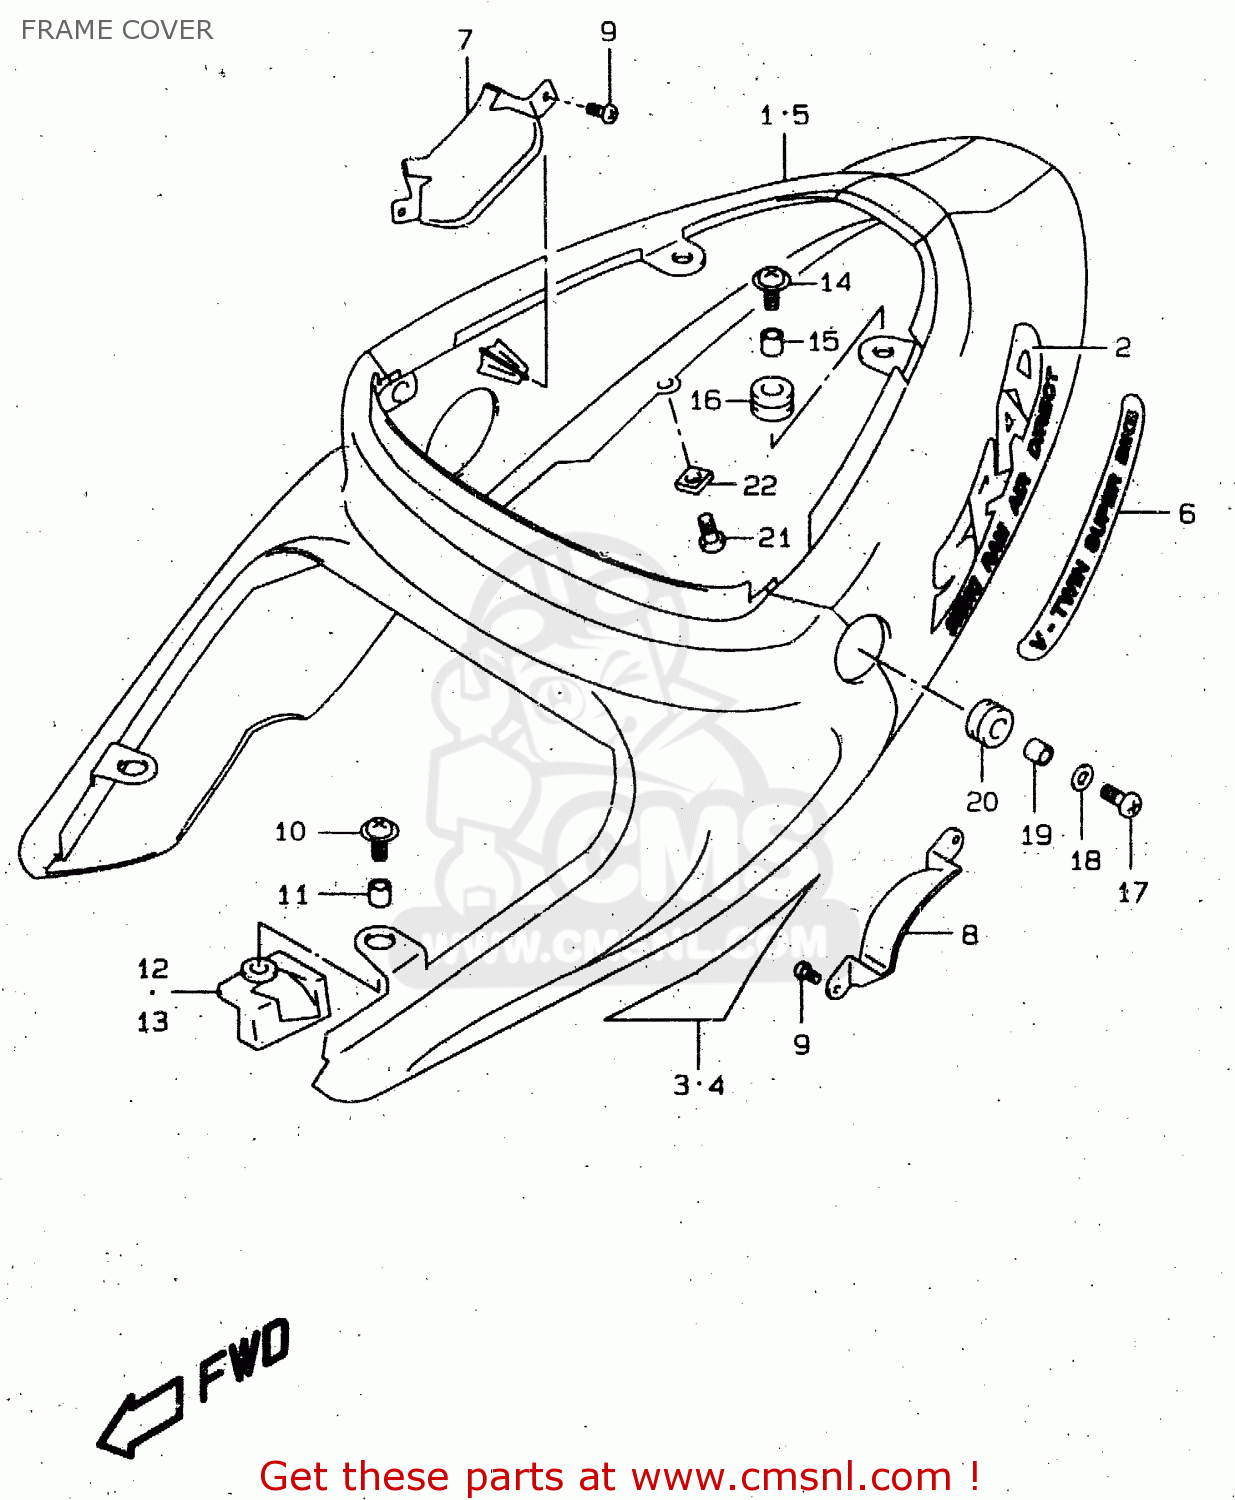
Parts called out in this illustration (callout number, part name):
1	COVER,FRAME,RIGHT
2	EMBLEM,FRAME COVER
3	TAPE,FRAME COVER,R(BLUE)
4	TAPE,FRAME COVER,L(BLUE)
5	COVER,FRAME
6	EMBLEM,FRAME COVER
7	CAP,FRAME COVER HOLE,R
8	CAP,FRAME COVER HOLE,L
9	SCREW
10	SCREW(6X20)
11	SPACER(6.5X9X9)
12	CUSHION,FRAME COVER,R
13	CUSHION,FRAME COVER,L
14	SCREW(6X20)
15	SPACER(6.5X10X9.4)
16	CUSHION
17	SCREW(6X20)
18	WASHER(6.5X22X1.6)
19	SPACER(6.5X9X6.7)
20	CUSHION
21	SCREW
22	NUT
